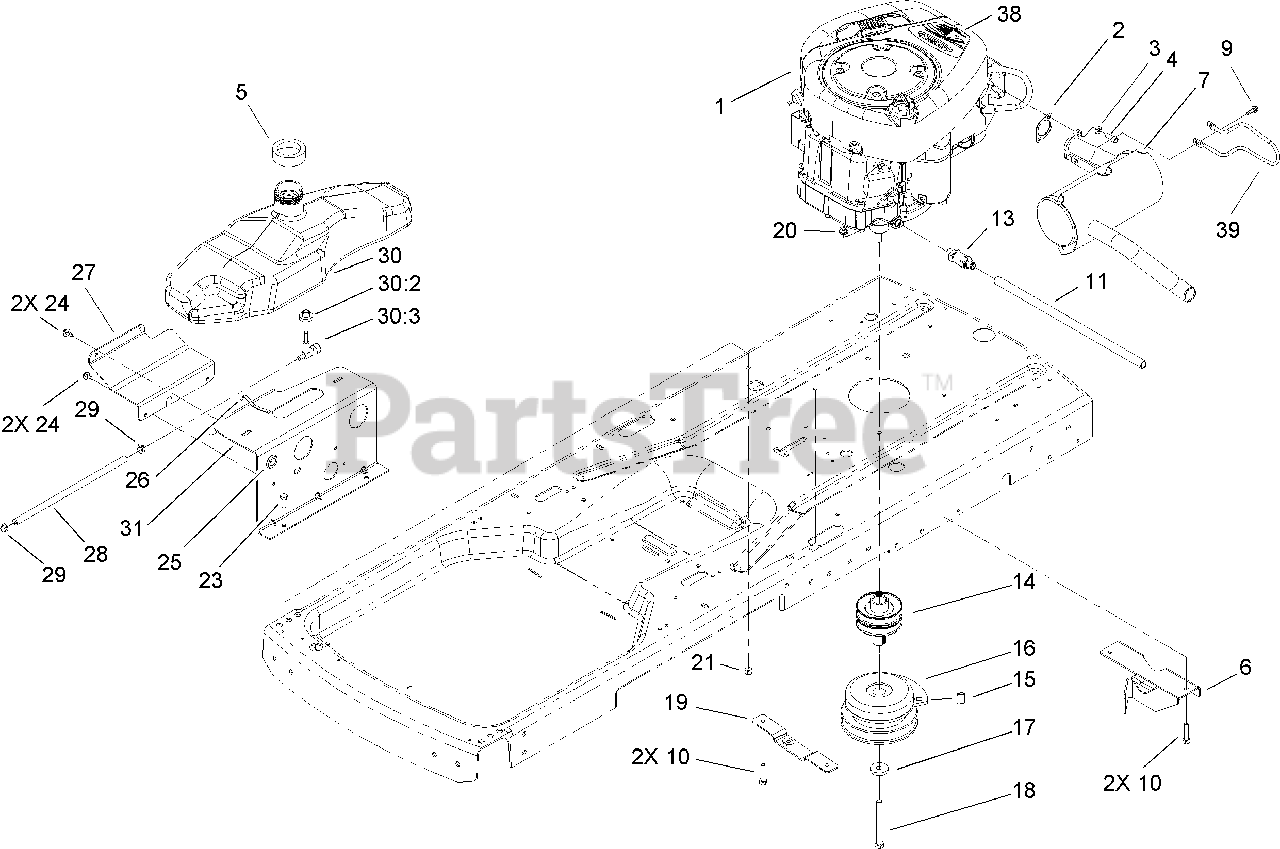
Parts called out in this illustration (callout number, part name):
2	GASKET-MUFFLER
3	WASHER-LOCK
4	SCREW-HSH
5	SEAL-FOAM
6	BRACKET-PIVOT
9	SCREW-HWH
10	SCREW-HH
11	TUBE-DRAIN, OIL
13	VALVE-DRAIN, OIL
14	PULLEY-ENGINE
16	CLUTCH-ELECTRIC
18	SCREW-HH
19	PLATE-MOUNT, IDLER
21	NUT-LOCK, NI
23	SCREW-HH
24	SCREW-HHF
27	PLATE-SUPPORT
28	HOSE-FUEL
30	FUEL TANK ASM
30:3	VALVE-FUEL
38	DECAL-ENGINE
39	GUARD-MUFFLER
